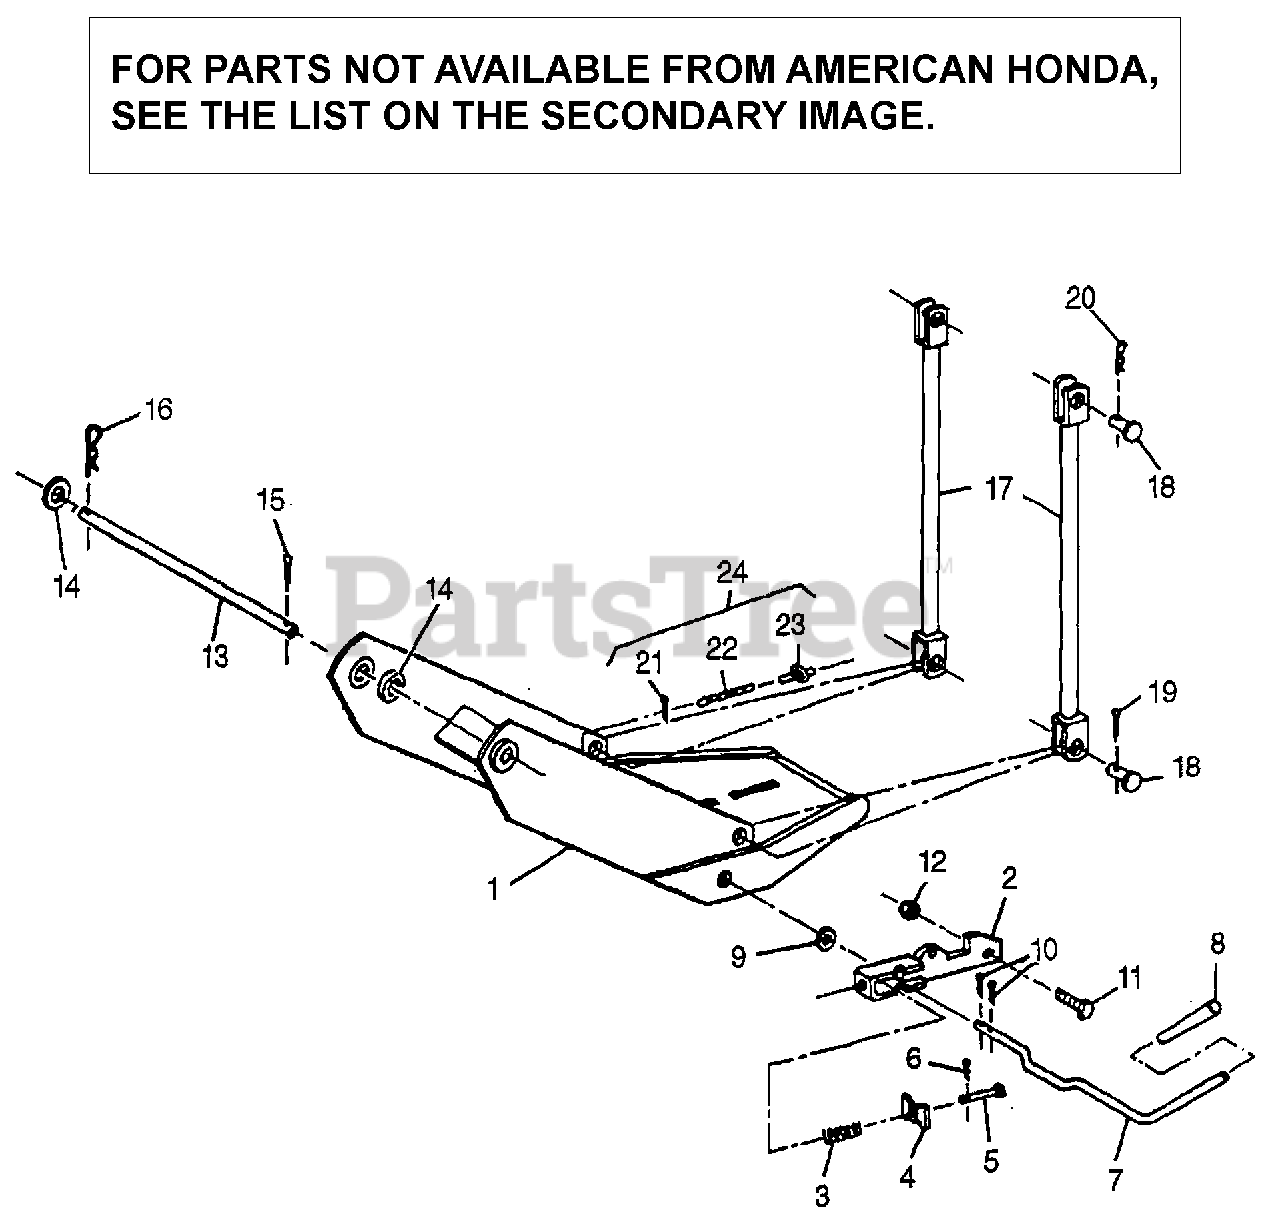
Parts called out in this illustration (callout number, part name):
2	LATCH, QUICK HITCH
4	PLATE, SPRING
5	PIN (1/4X1-3/4")
7	LEVER, ATTACHING
13	ROD, PIVOT (NOT AVAILABLE)
17	LINK, LIFT
18	PIN, CLEVIS
